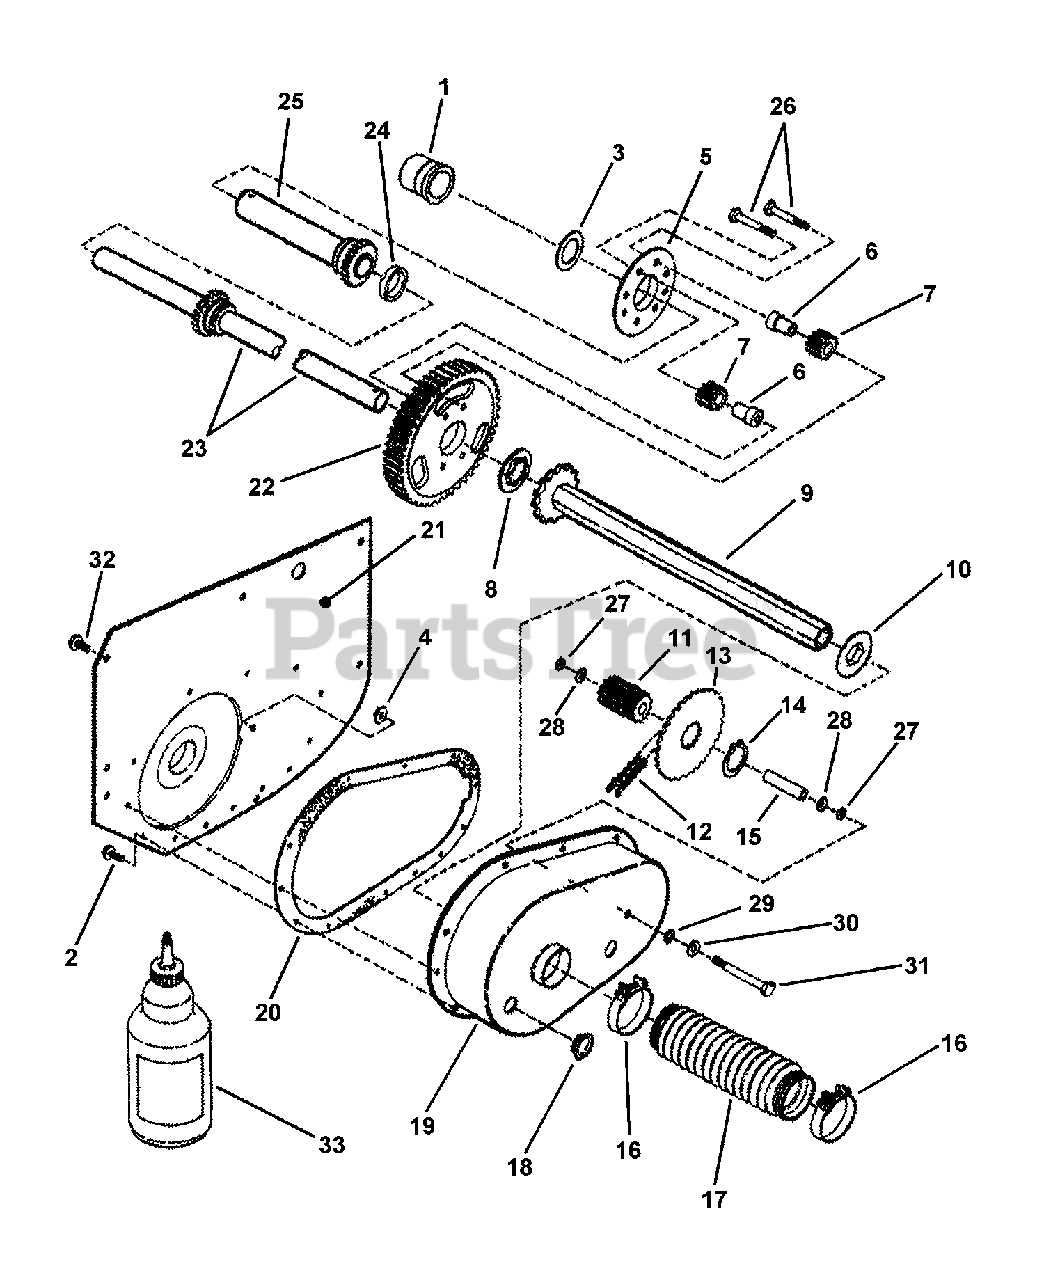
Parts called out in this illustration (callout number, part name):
1	ASSEMBLY, R.H. Fender Bearing & DX Bearing
2	SCREW, 1/4-20 x 5/8" Hex Washer Head Self-Tap
3	WASHER, Thrust
4	NUT, 5/16-24 Flange Lock (Large)
5	PLATE, Differential
6	SPACER, Pinion
7	GEAR, Differential Pinion (12T 12P)
8	WASHER, Thrust
9	ASSEMBLY, Drive Hex Tube
10	WASHER, Hex Insert (nylon)
11	GEAR, 11 Tooth, 10 Pitch
12	CHAIN, 46 Pitch (#35 Endless)
13	SPROCKET, 34T, 3/8P
14	RING, 1-3/16" External Retaining
15	SPACER, Differential Case
16	BOOT CLAMP (for 2" Hose)
17	BOOT, Oil Seal (Short Axle)
18	PLUG, 1/2" Cup Insert
19	CASE, Transmission
20	GASKET, Transmission Case
21	FENDER, R. H. (1.62" Dia. Hole)
22	GEAR, 63 Tooth 10 Pitch
23	AXLE, Long
24	SPACER, Differential Case
25	ASSEMBLY, Short Axle, 23T (Includes Gear)
26	BOLT, 5/16-24 x 1-5/8" Hex Special Lock (Vibresist)
27	O-RING, 5/16"
28	WASHER, 5/16" Belleville
29	WASHER, 5/16" External Tooth Lock
30	WASHER, .34 x .69 x .08 Flat
31	SCREW, 5/16-24 x 2-5/8" Hex Head Cap
32	SCREW, 5/16-18 x 5/8" Hex Washer Self-Tap
33	GREASE, Transmission (24 oz. Required)
